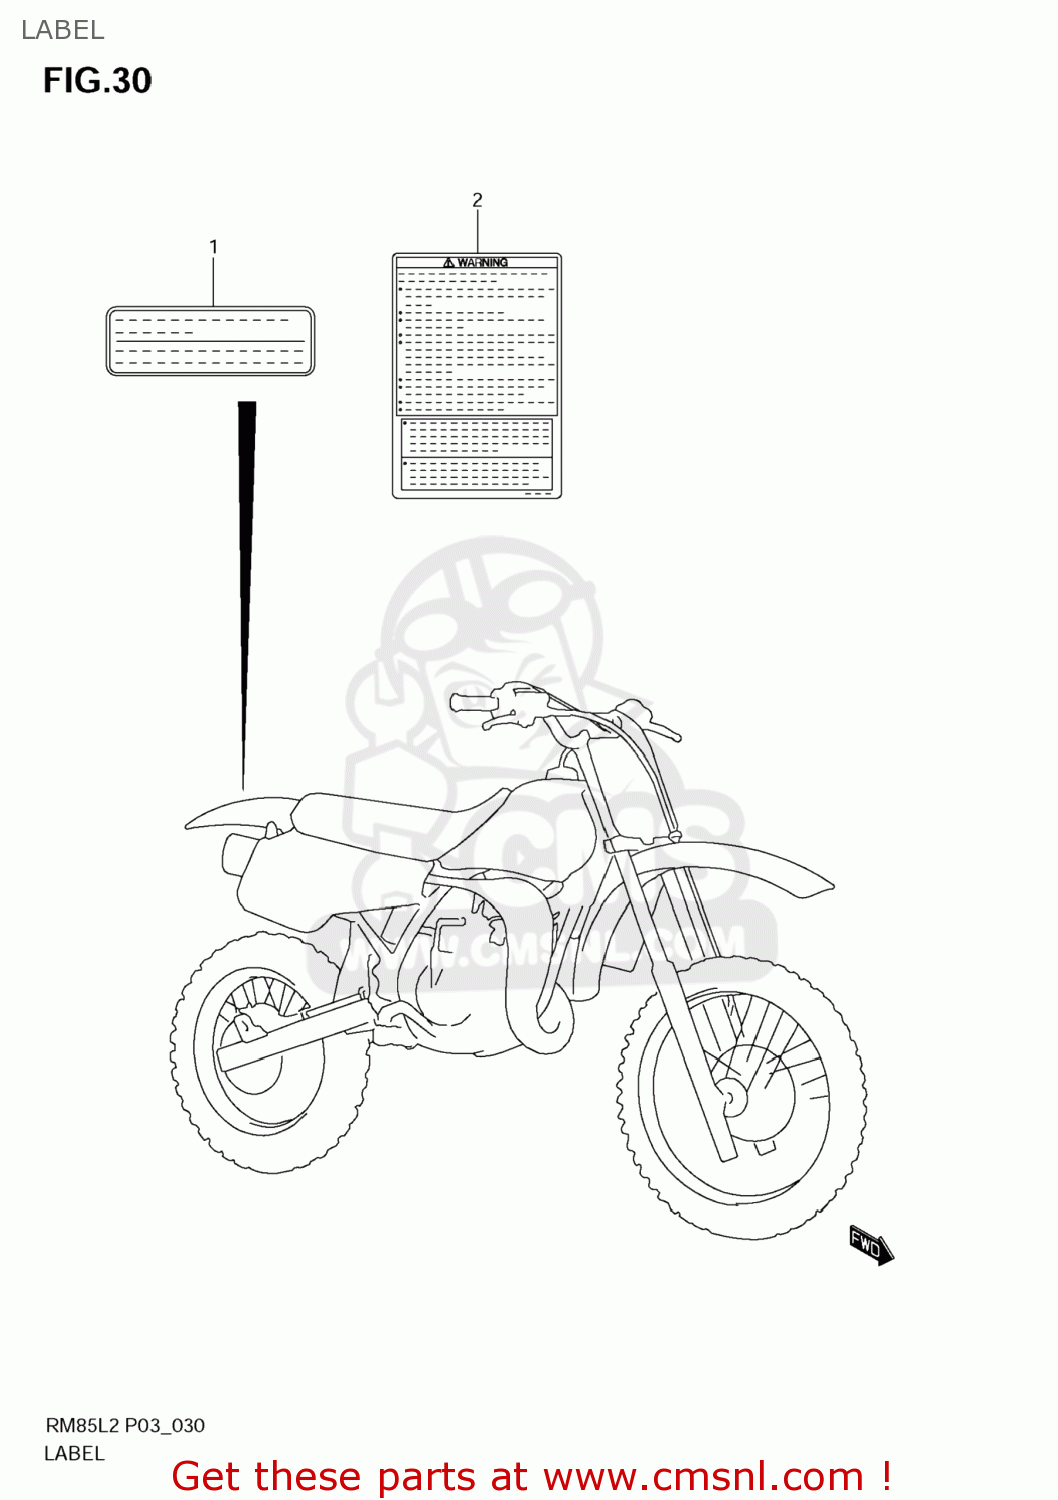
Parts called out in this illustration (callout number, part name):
1	LABEL,WARNING NO.2
2	LABEL,WARNING
3	MANUAL,OWNER'S
